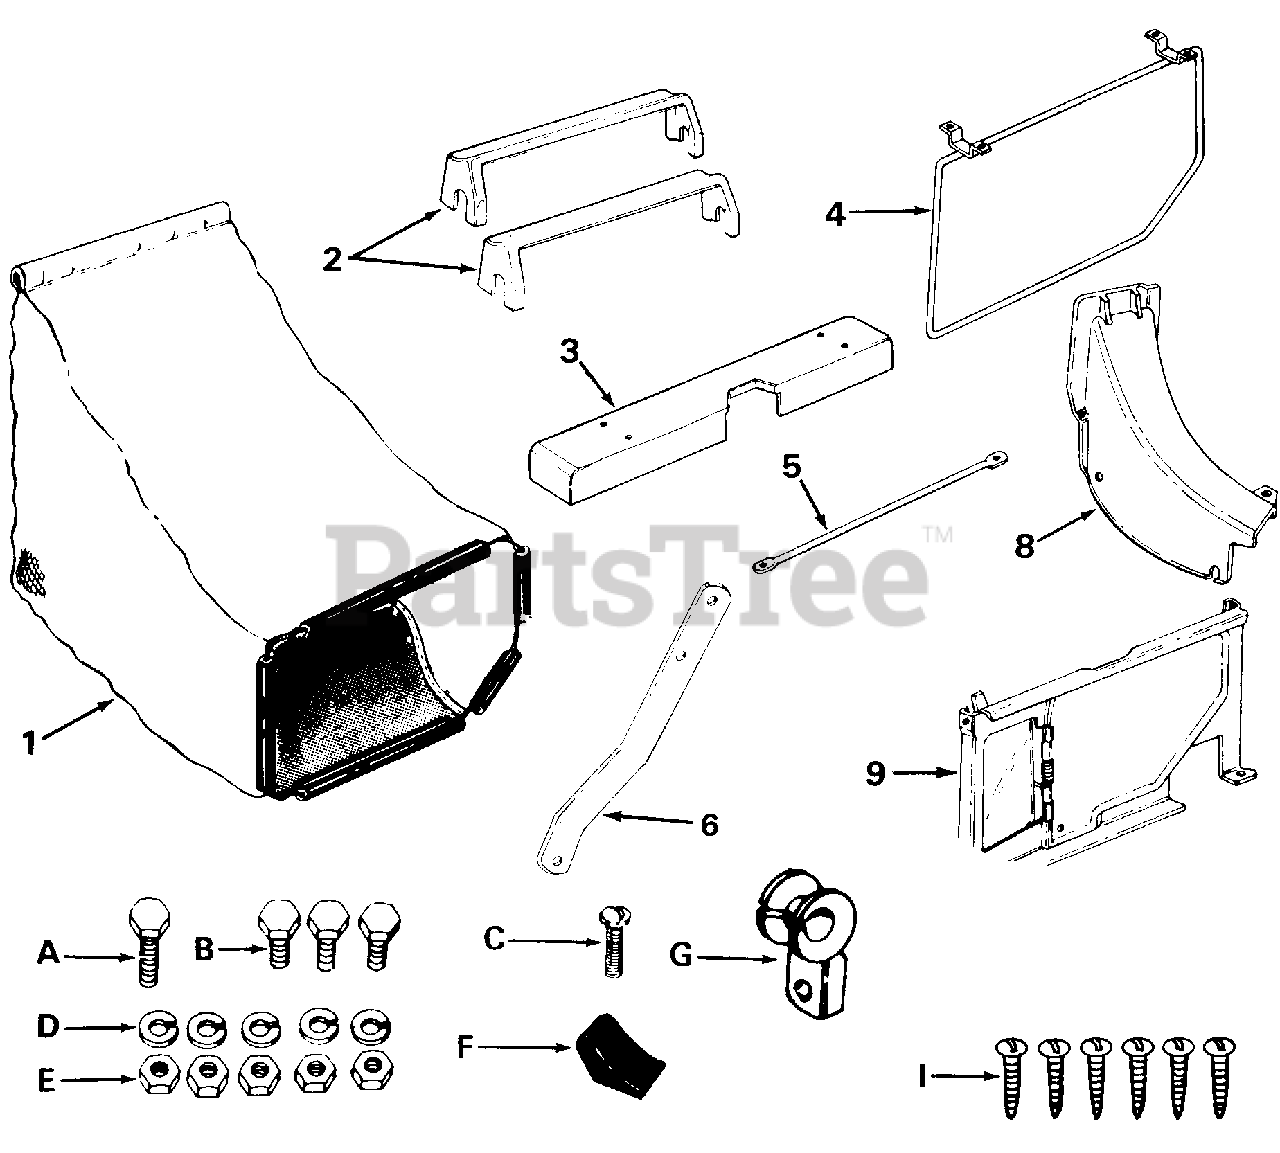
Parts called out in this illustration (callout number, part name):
1	Grass Bag
2	Grass Catcher Handle
3	Catcher Frame Cover
4	Front Catcher Frame
5	Bag Support
6	Panel Support Bracket
8	Top Discharge Chute
9	Top Catcher Panel
A	Hex Bolt 1/4-20 x 5/8" Lg.*
B	Hex Bolt 1/4-20 x 1/2" Lg.*
C	Truss Machine Screw 1/4-20x 3/4" Lg.*
D	Lock Washer 1/4" I.D.*
E	Hex Nut 1/4-20 Thread
F	Door Grip
G	Rope Guide
I	Truss Machine Self-Tap Screw 1.0" Lg.
